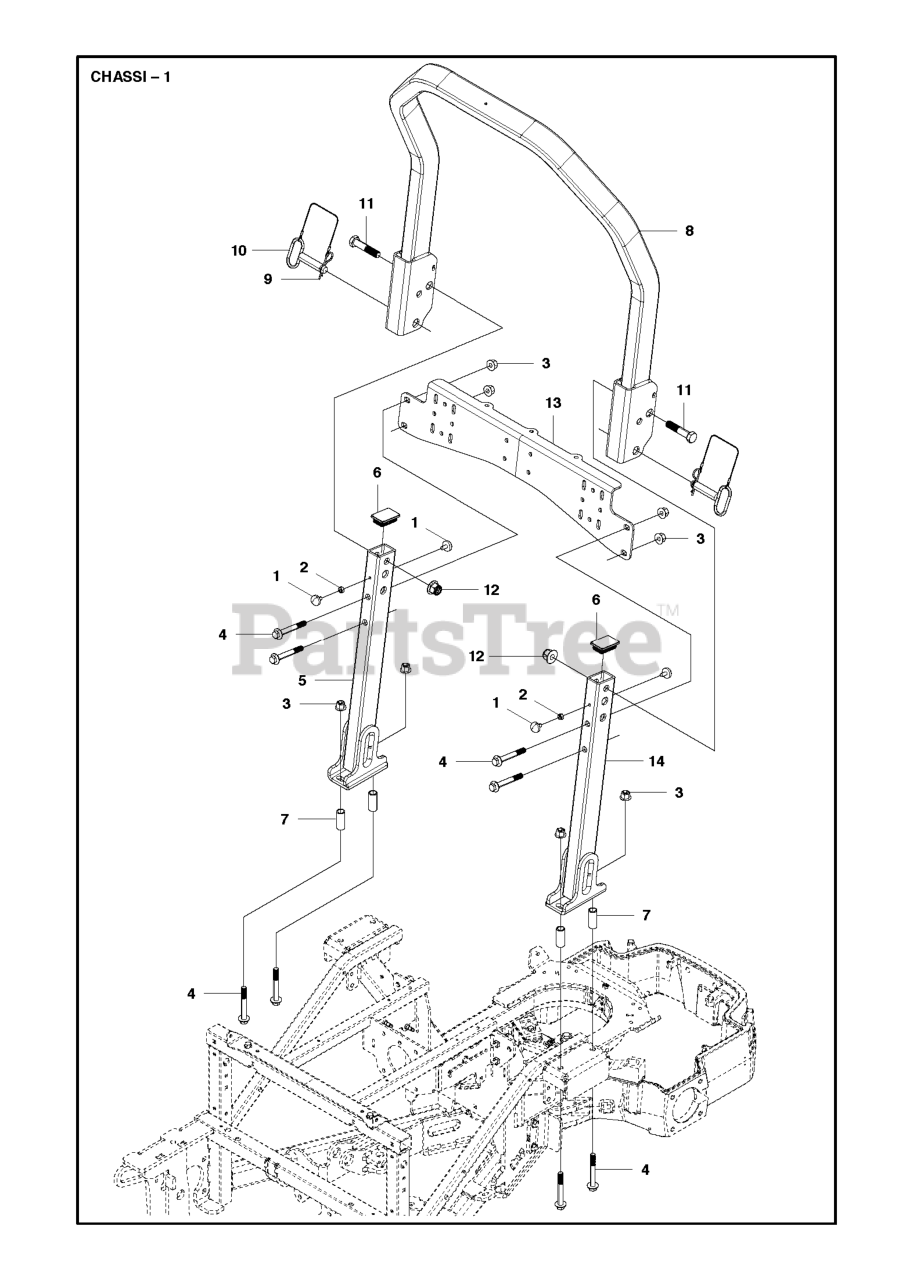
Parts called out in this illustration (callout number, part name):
1	ANTIVIBRATION ELEMENT
2	NUT
7	SPACER
